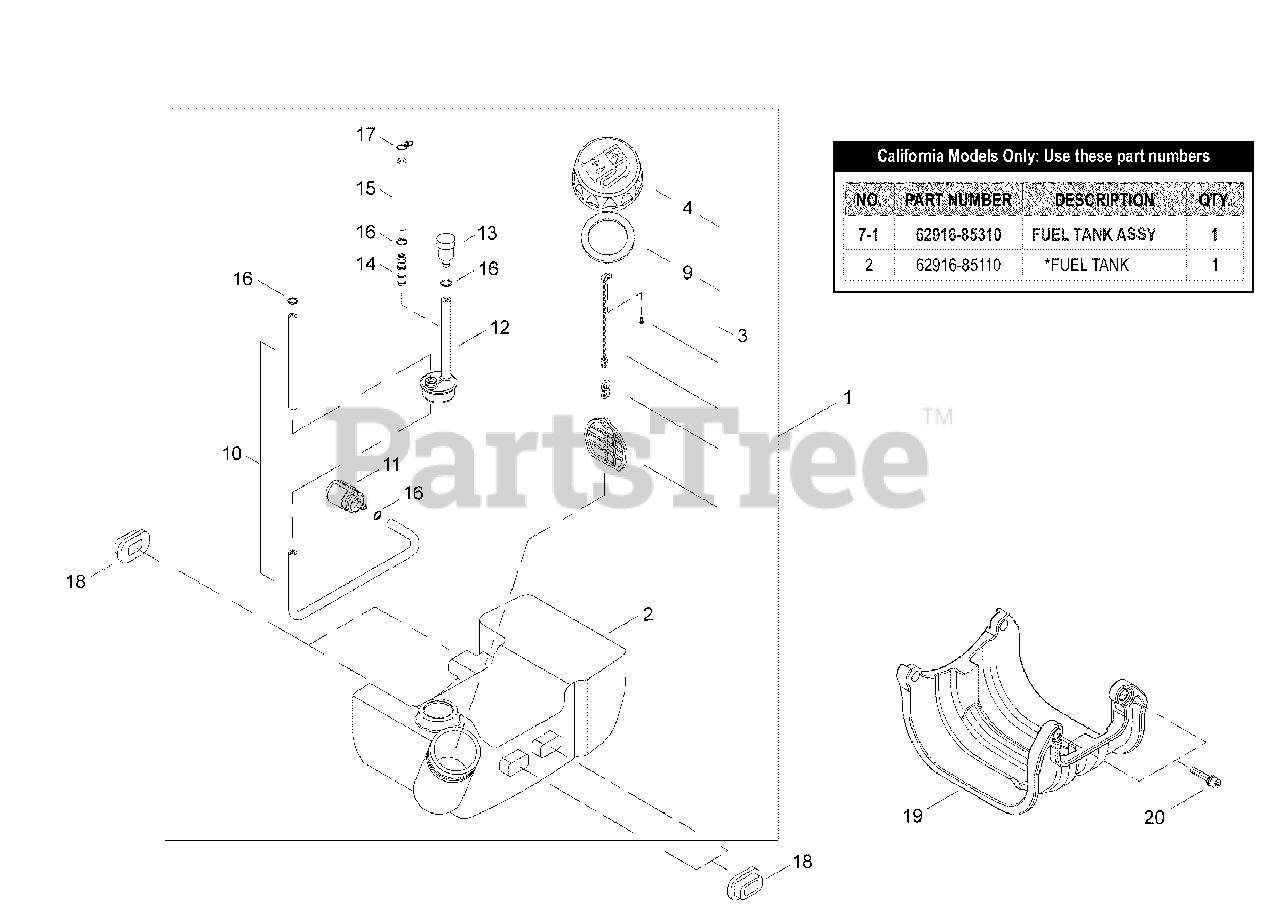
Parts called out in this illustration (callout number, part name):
1	TANK ASSY, FUEL
2	TANK, FUEL
3	CAP ASSY, FUEL
4	CAP, FUEL
9	GASKET, FUEL CAP
10	PIPE, FUEL
11	FILTER, FUEL 125-528
12	GROMMET, FUEL W/VENT PIPE
13	VENT ASSY
14	CONNECTOR, PIPE
15	PIPE, FUEL RETURN
16	CLIP Ø6
17	CLIP, SPRING Ø5.2
18	CUSHION, FUEL TANK
19	GUARD, PLASTIC FUEL TANK
20	BOLT M5×20
